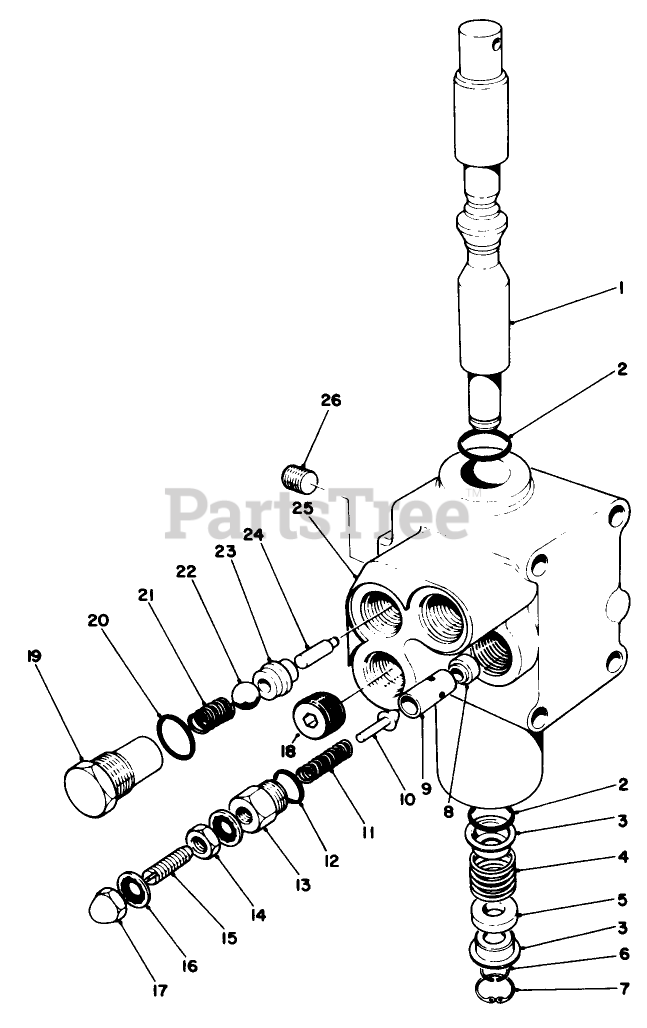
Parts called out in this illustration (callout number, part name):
1	SPOOL
2	O-RING
3	RETAINER
4	SPRING
5	FLOAT SPACER
6	RING-SNAP
7	RING-SNAP
8	SEAT-RELIEF
9	Guide
10	Plunger
12	"O"Ring
13	Cap-PV Adjustment
14	Nut
15	Screw-Set
16	Stat O Seal
17	Nut-Accorn
20	O-RING
21	SPRING
23	SEAT-VALVE
